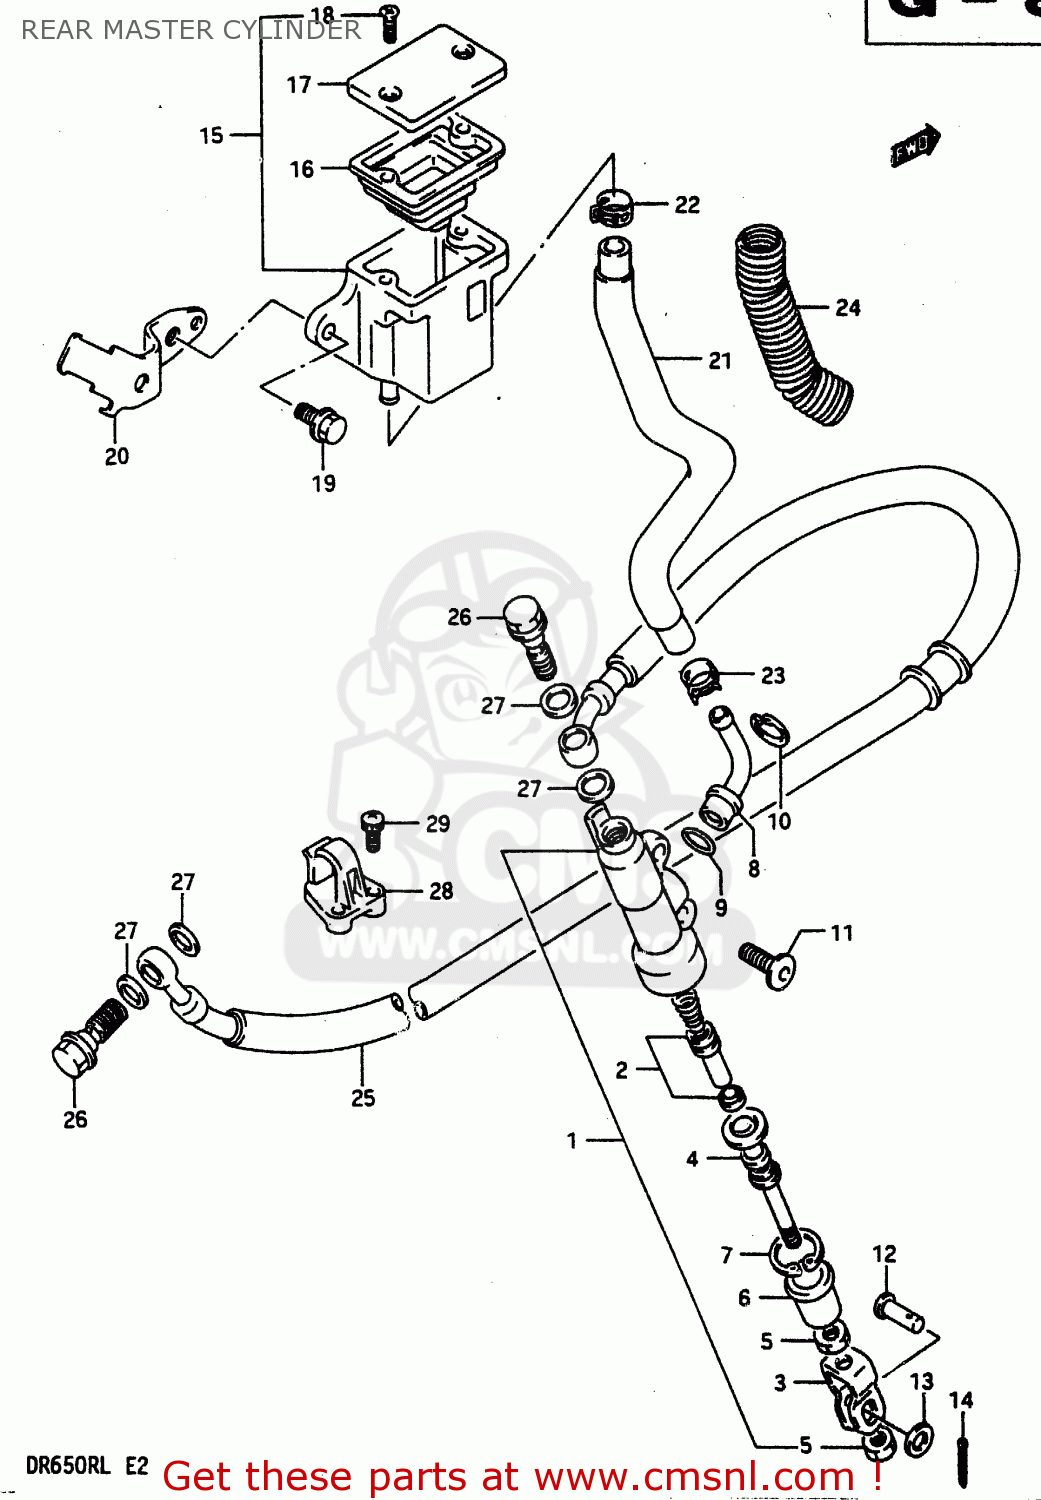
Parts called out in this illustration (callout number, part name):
1	CYLINDER ASSY,RR MASTER
2	PISTON/CUP SET
3	YOKE
4	ROD,PUSH
5	NUT
6	BOOT
7	CIRCLIP
8	CONNECTOR
9	O RING
10	CIRCLIP
11	BOLT(6X18)
12	PIN
13	WASHER
14	PIN
15	TANK ASSEMBLY,RESERVOIR
16	DIAPHRAGM
17	CAP
18	SCREW
19	BOLT
20	PLATE COMP,RESERVOIR T
21	HOSE COMP,RESERVOIR TANK
22	CLIP
23	CLAMP
24	SHIELD,RESERVOIR TANK HOSE
25	HOSE COMP,REAR BRAKE
26	BOLT UNION
27	WASHER(10X15X1.5)
28	GUIDE,RR BRAKE HOSE
29	SCREW
